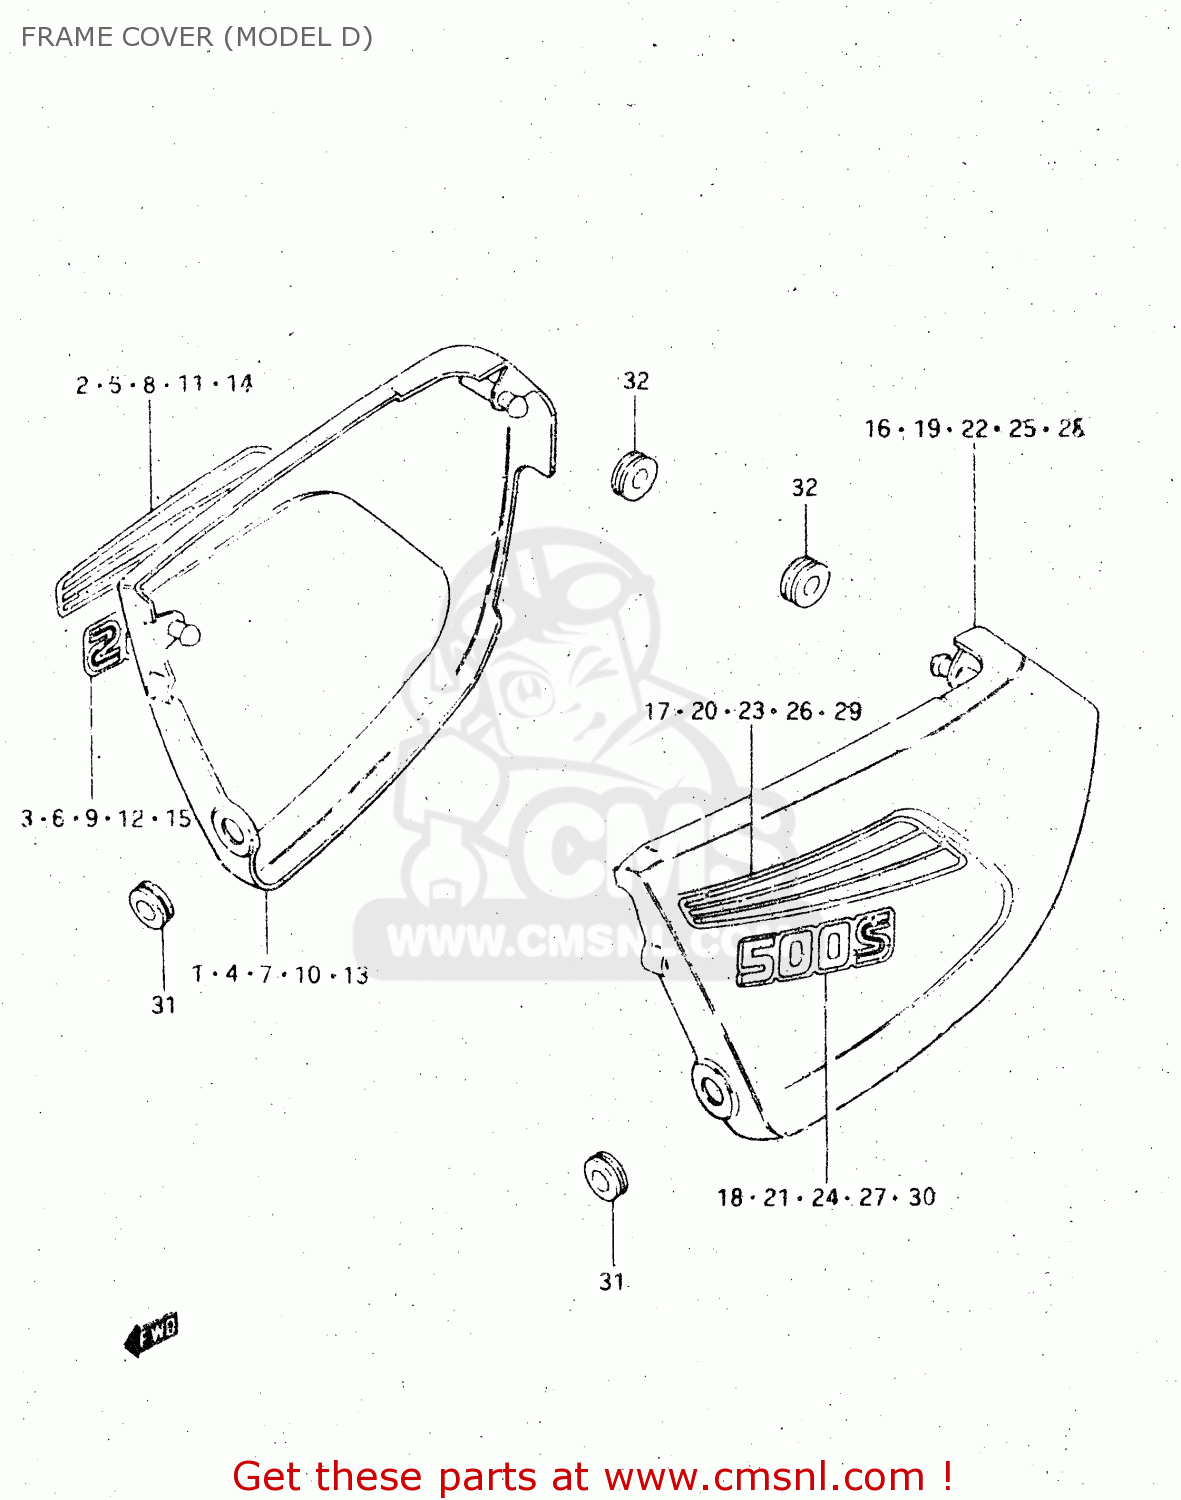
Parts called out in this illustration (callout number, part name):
1	COVER, FRAME RH (BLACK)
2	TAPE, FRAME COVER RH
3	EMBLEM
4	COVER, FRAME RH (BLUE)
5	TAPE, FRAME COVER RH
6	EMBLEM
7	COVER,FRAME,RIGHT
8	TAPE, FRAME COVER RH
9	EMBLEM
10	COVER,FRAME,RIGHT
11	TAPE SET,FRAME COVER,RIGHT
12	EMBLEM
13	COVER, FRAME RH (YELLOW)
14	TAPE, FRAME COVER RH
15	EMBLEM
16	COVER, FRAME LH (BLACK)
17	TAPE, FRAME COVER LH
18	EMBLEM
19	COVER, FRAME LH (BLUE)
20	TAPE, FRAME COVER LH
21	EMBLEM
22	COVER,FRAME,LEFT
23	TAPE, FRAME COVER LH
24	EMBLEM
25	COVER,FRAME,LEFT
26	TAPE SET,FRAME COVER,LEFT
27	EMBLEM
28	COVER, FRAME LH (YELLOW)
29	TAPE, FRAME COVER LH
30	EMBLEM
31	CUSHION
32	CUSHION
